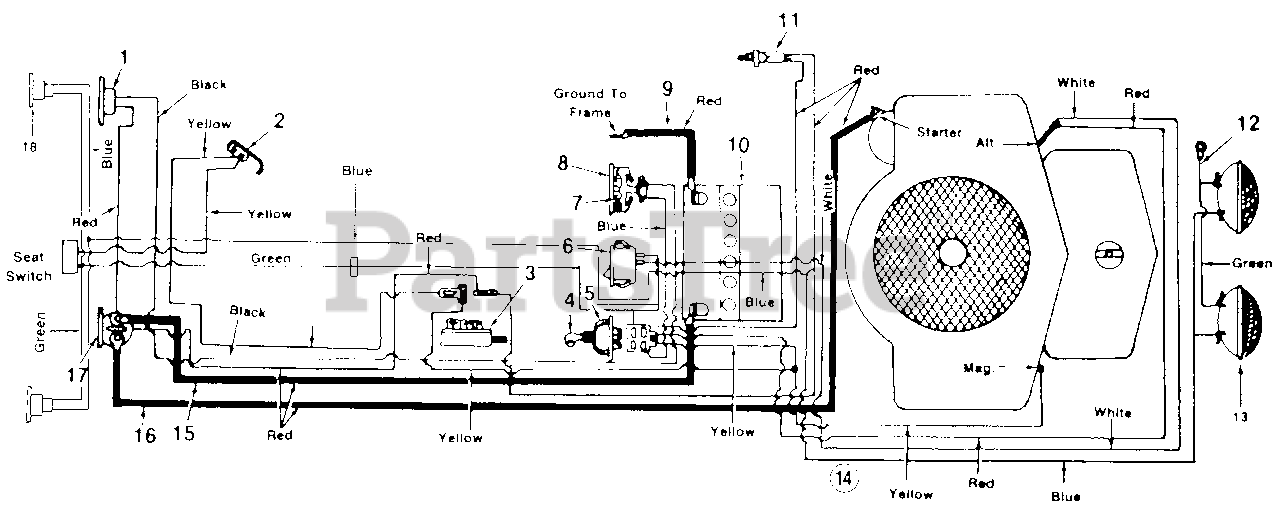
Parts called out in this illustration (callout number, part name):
1	Circuit Breaker
2	Spring Switch
3	Safety Switch Dpst.
4	Ignition Key
5	Ignition Switch
6	Headlight Switch
7	Foam Strip
8	Ammeter
9	Grounding Wire 14.0" Lg.
10	12 Volt Battery
11	Safety Switch
12	Ground Wire
13	Headlight
14	Wire Harness
15	Electric Wire 27.0" Lg.
16	Electric Wire 32.5" Lg.
17	Solenoid
18	Taillight
